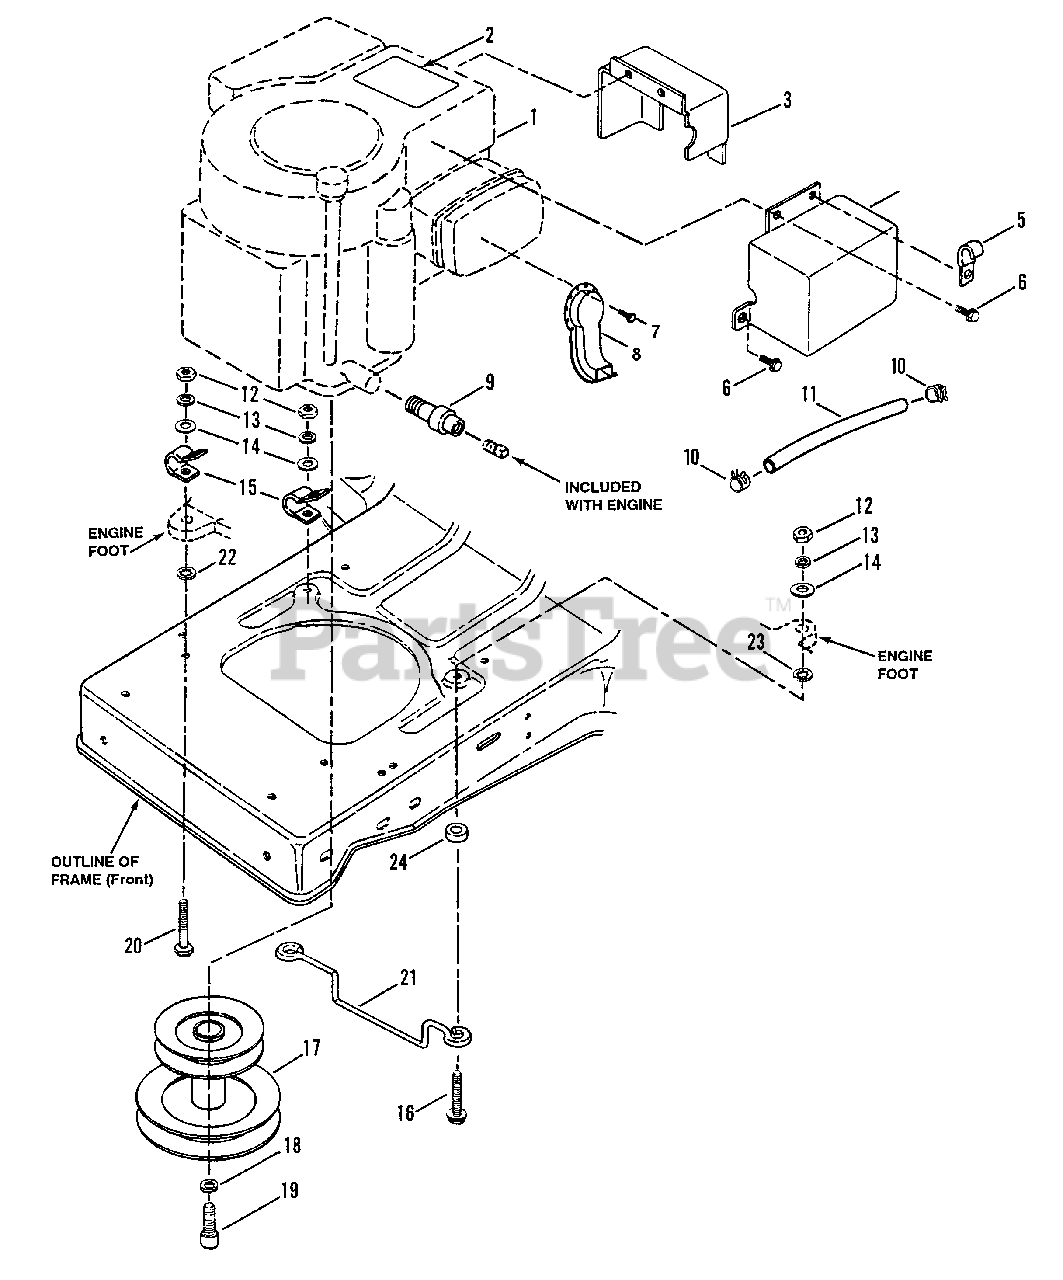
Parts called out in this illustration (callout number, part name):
2	DECAL, 14HP Brigg's & Stratton
3	HEAT SHIELD, Valve Cover
4	HEAT SHIELD, Muffler
5	CLIP, "J" Type
6	BOLT, 1/4-20 x 1/2' Hex Flange Lock
7	SCREW, #8-18 x 1/2' Hex Hd., Self-Tap.
8	EXTENSION, Muffler
9	EXTENSION, Oil Drain (Short)
10	CLAMP, Fuel Line
11	LINE, Fuel
12	NUT, 5/16-18 Hex
13	WASHER, 5/16 Split Lock
14	WASHER, 5/16 Flat
15	CLIP, Harness
16	SCREW, 5/16-18 x 2' Hex Hd. Cap
17	PULLEY ASSEMBLY
18	WASHER, 7/16 Split Lock
19	SCREW, 7/16-20 x 1" Hex Cap, Skt. Hd.
20	SCREW, 5/16-18 x 1 3/4" Hex Hd. Cap
21	GUIDE, Belt
22	WASHER, 5/16 Internal Tooth Lock
23	RETAINER, 5/16 Bolt
24	SPACER, .625 O.D., .342 I.D. x.370
